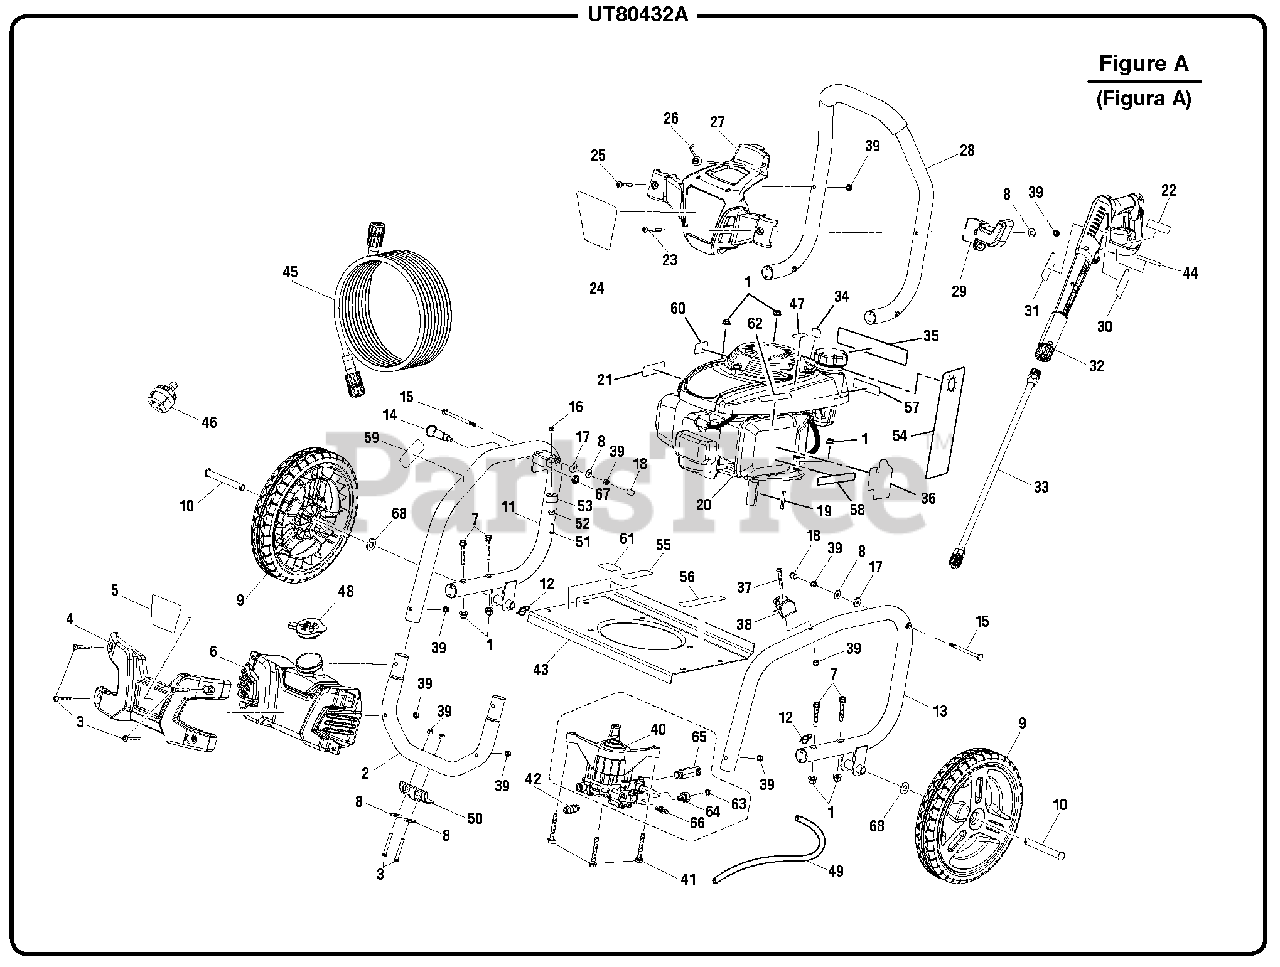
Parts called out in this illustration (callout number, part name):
1	Lock Nut (M8 x 1-1/4 in.)
2	Front Frame
3	Screw (1/4-20 x 2 in.)
4	Detergent Tank Cover
5	Logo Label (Homelite)
6	Detergent Tank
7	Bolt (M8 x 55 mm)
8	Washer (1/4 in.)
11	Main Frame Assembly
12	Spring pin
13	Main Frame Assembly (Left)
14	Handle Release Knob
15	Bolt (1/4-20 x 3.5 in.)
16	Flange Nut (M4 x 0.7)
19	Output Shaft Key
21	Hot Surface Label
22	Trigger Handle Warning Label
23	Screw (1/4-20 x 2.27 in.)
24	Performance Label
25	Screw (1/4-20 x 1.65 in.)
26	Bungee Cord Assembly
27	Hose Storage
28	Handle Assembly
29	Trigger Handle Holder
30	Trigger Handle Warning Label
31	Logo Label
32	Trigger Handle Assembly
33	Spray Wand
34	E85 Label
35	Danger Label
36	Engine Control Label
37	Bolt (1/4-20 x 1.85 in.)
38	Spray Wand Holder
39	Lock Nut (1/4-20)
40	Pump
41	Bolt (M8 x 60 mm)
42	Thermal Release Valve
43	Engine Plate
44	Trigger Handle Spec Label
45	High Pressure Hose (25 ft.)
46	5-in-1 Change Over Nozzle
47	Release Water Label
49	Injection Hose
50	Rubber Foot
51	Bolt (M4 x 12 mm)
52	Washer (M4)
53	Rubber Bumper
54	Warning Hang Tag
55	Data Label
56	Pump Quick Start Label
57	Combustion Warning Label
58	EMC Label
59	Hot Surface Label
60	Lubricant Label
61	Oil Dipstick Label
62	Inquiries Label
63	Filter Screen
64	Inlet Tube
65	Outlet Tube
66	Detergent Suction Kit
67	Lock Nut (1/2-20)
68	Washer (1/2 in.)
